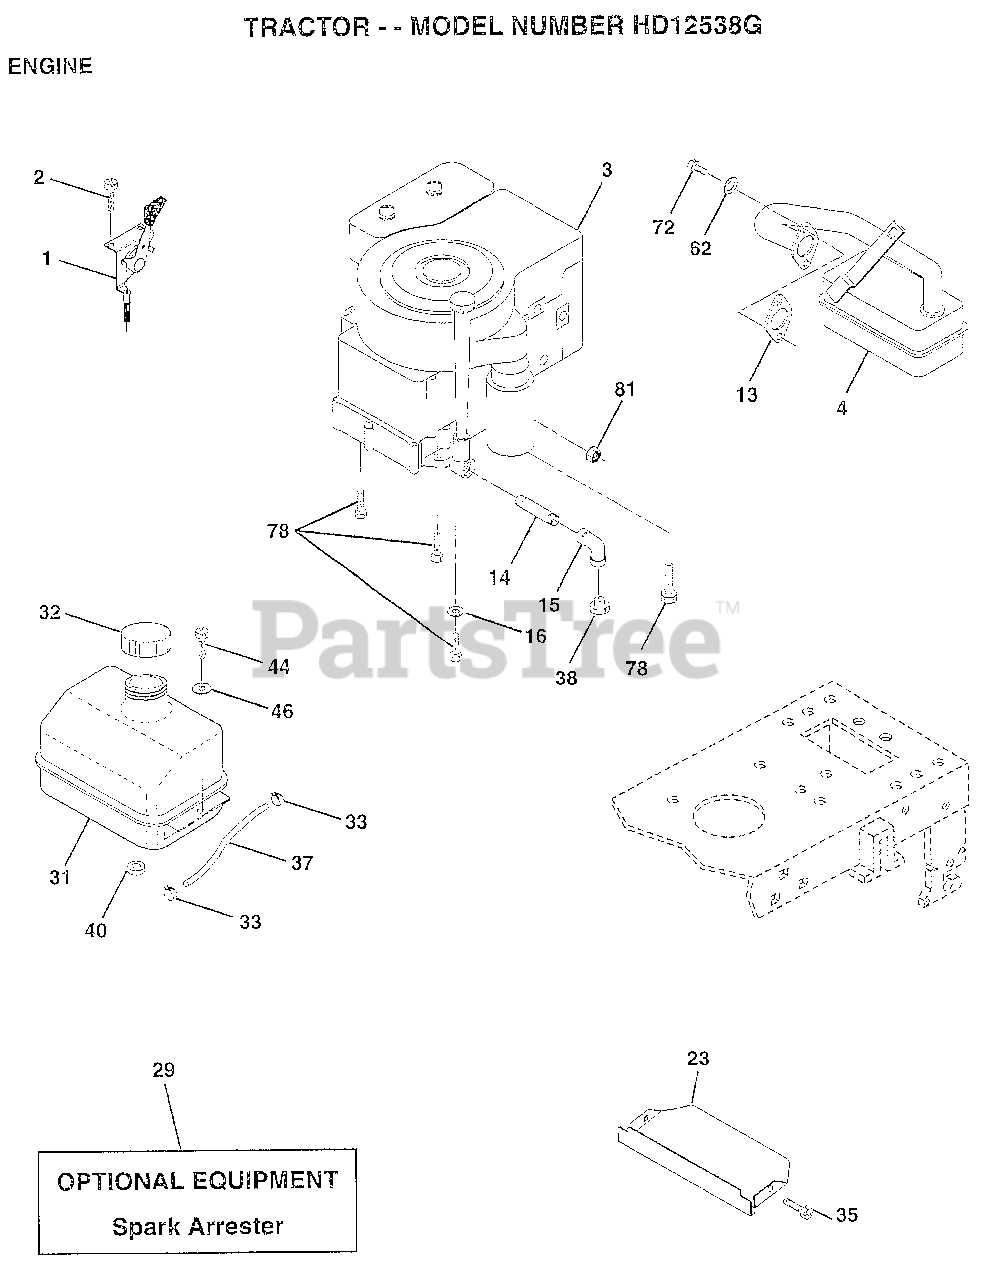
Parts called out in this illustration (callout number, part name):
1	CONTROL THROTTLE
2	SCREW LT
4	MUFFLER
13	GASKET ENG 1 313 LD TIN PLATED
14	PIPE NIPPLE
15	ELBOW
16	LOCKWASHER
23	SHIELD.BRN/DBR.GD
31	TANK.FUEL.LT.
32	CAP ASM FUEL
33	HOSE CLAMP
35	SCREW
37	LINE FUEL
44	SCREW HEX CRT
46	WASHER
62	LOCKWASHER
72	SCREW
78	SCREW
81	NUT
